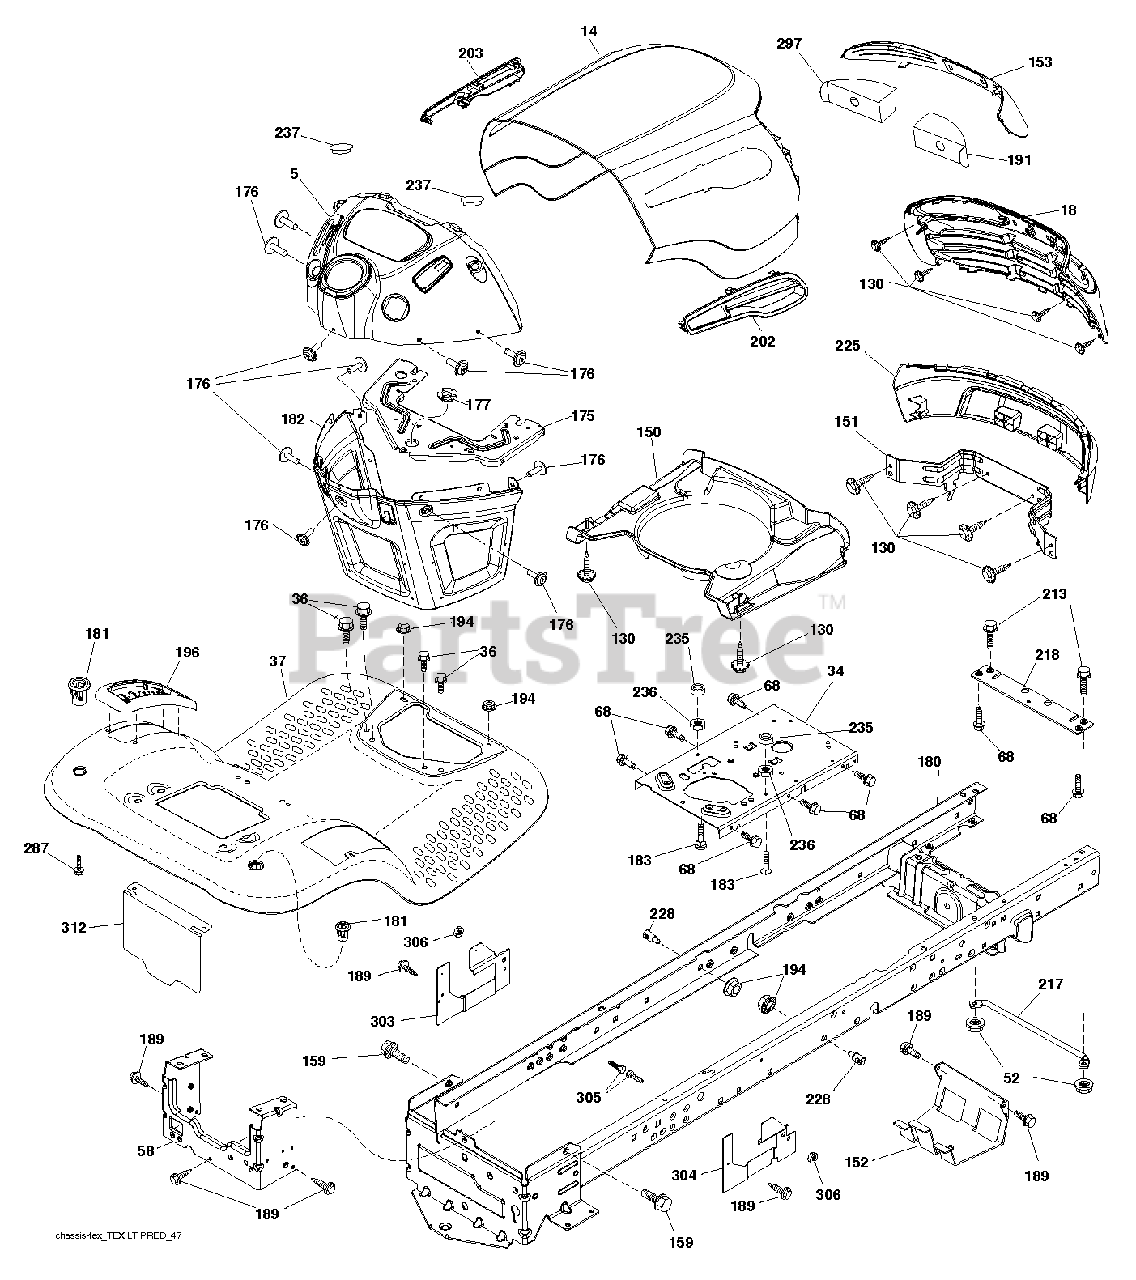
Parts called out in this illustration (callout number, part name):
34	PLATE.ENGINE.WELDED.CHASSIS
36	SCREW 5/16"
52	LOCKNUT
58	DRAWBAR UPPER 2PC SMALL FENDER
130	SCREW.#10 X 0.750.BOS THREAD
151	BRACKET.PIVOT.ALPHA.LT
152	SHIELD BROWNING
159	SCREW, 3/8-16X3/4
175	CROSSMEMBER
176	SCREW.#10-24X5/8.RN.QU
177	BUSHING STEERING
180	CHASS.WLDMNT.TL.12GA/2P.48/54
181	FEND/FTRST.PCH.CPH.NFW
182	DASH.LWER.PREDATOR/HUSQ.LT
183	BOLT.5/16-18X1-1/4 FULL THD
189	SCREW
191	INSERT.REFLECT.PREDATOR.LT.RH
194	NUT LOCK HEX FLANGE 5/16-18
196	CONSOLE.ASM.DECKLFT.BL/RBT.TLT
213	BOLT
217	ROD.PIVOT.HOOD
218	X-PIECE.HOOD.STOP.NON/
228	STUD.FASTNER.W/ANTI-ROTATE
235	SPACER FENDER
236	NUT.CENTERLOCK.5/16-
237	PLUG.MOUNT.CARGO.BLK
297	REFLECTOR.INSERT.PRED.LH.LT
306	NUT LOCK FLG 3/8-16 UNC
